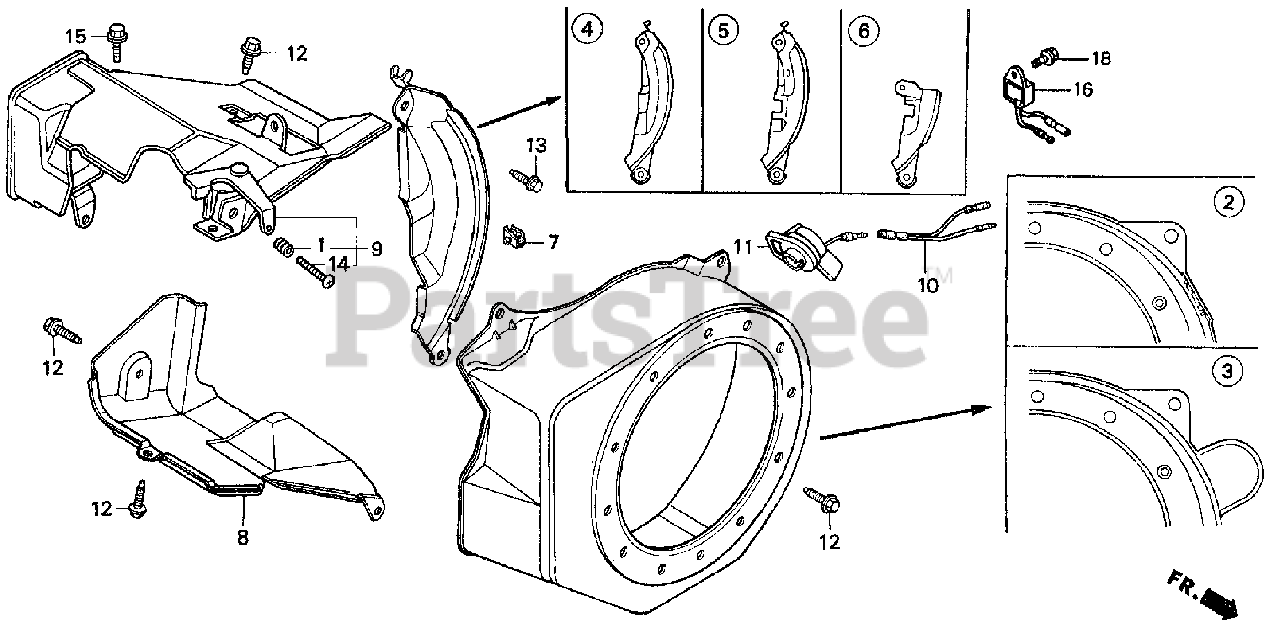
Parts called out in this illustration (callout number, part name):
2	COVER, FAN *R8* (BRIGHT RED)
4	PLATE, SIDE (OIL ALERT)
4	PLATE, SIDE (STD)
4	PLATE, SIDE
7	CLAMP, CORD
7	CLIP, HARNESS
8	SHROUD
10	SUB-HARNESS
11	SWITCH ASSY., ENGINE STOP
12	BOLT, FLANGE (6X12) (CT200)
13	BOLT, FLANGE (6X20) (CT200)
16	ALERT UNIT, OIL
18	BOLT, FLANGE (6X8)
